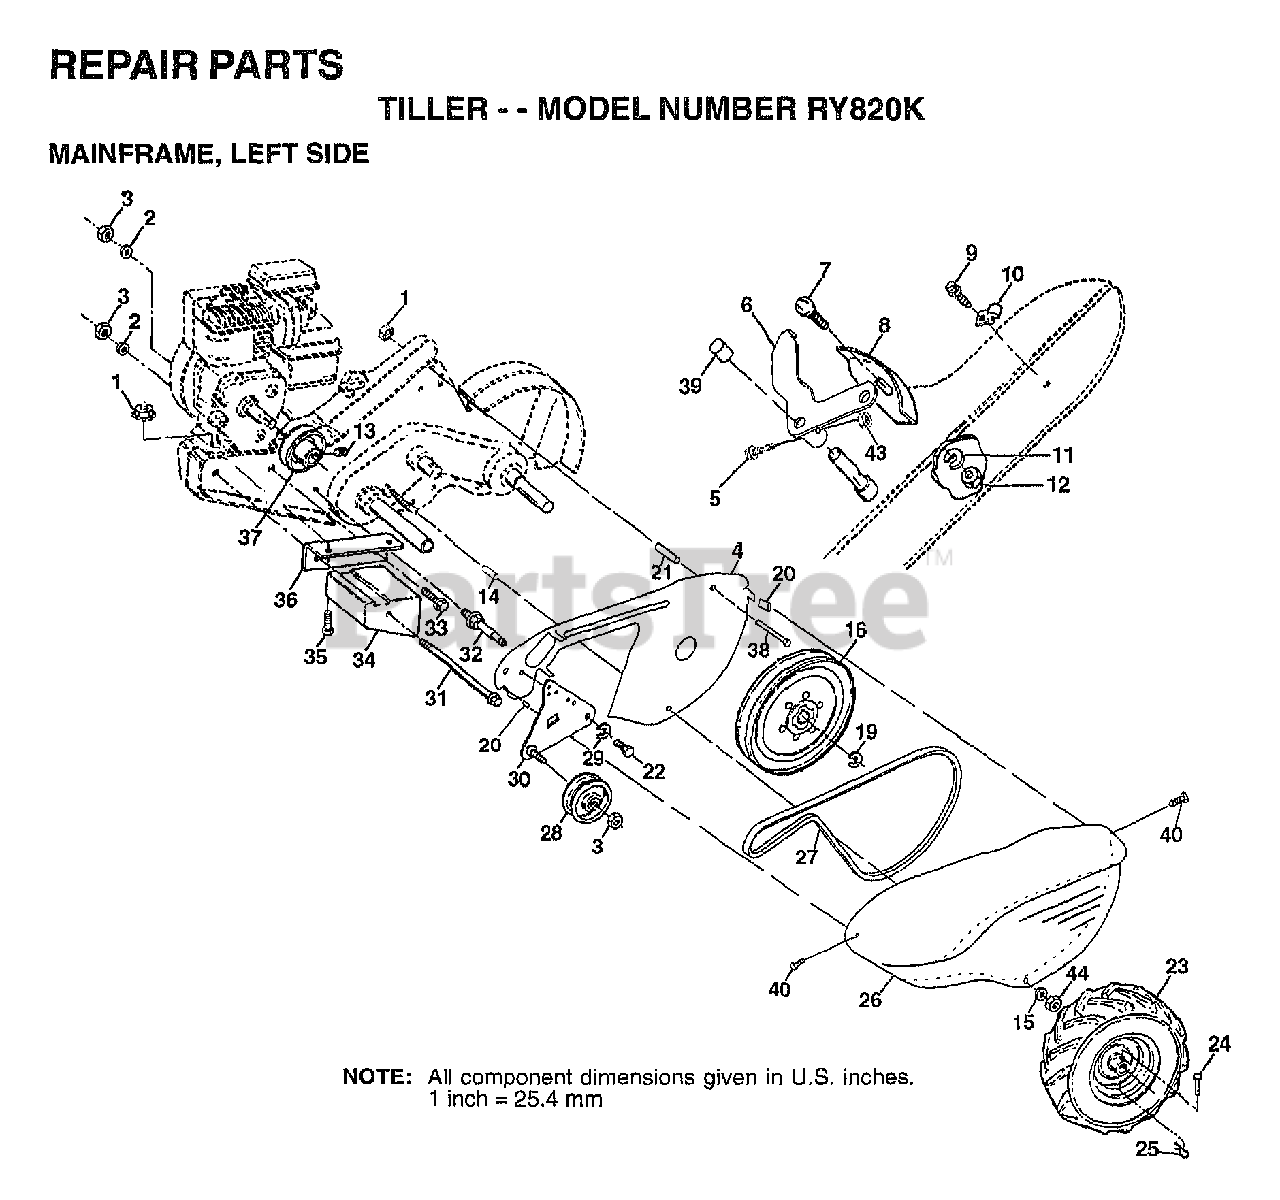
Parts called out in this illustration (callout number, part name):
2	LOCKWASHER
3	NUT.HEX.3/8-16UNC
4	SHIELD.INNER.BELT
5	"SCREW-LEVER,SHI"
6	LEVER ASM CRT
7	BOLT
8	PANEL TI
10	CONDIUT CLIP T
11	LOCKWASHER
13	SET SCREW
14	SPACER-SPLIT
15	WASHER
16	SHEAVE.TRANS.
20	NUT J CLIP #8
21	SPACER CRT
22	BOLT.FIN.HX.5/16-24X1/2
23	TIRE.CHV.13X5.0-6
24	RIVET.DRILL.1.75
25	RETAINER M
26	GUARD.BELT
27	BELT-V
28	PULLEY-IDLER TI
29	KLIP RING
30	BRACKET ASM IDLER
31	BOLT CRT
32	SHIFT ARM CRT
33	BOLT
34	COUNTERWEIGHT CRT
35	BOLT.HEX.5/16-1.5
36	BRACKET LH CRT
37	ENGINE PULLEY
39	CAP PLUNGER BLACK
40	SCREW HX WSH.HD#8-18X1/2
43	LOCKNUT
44	NUT
